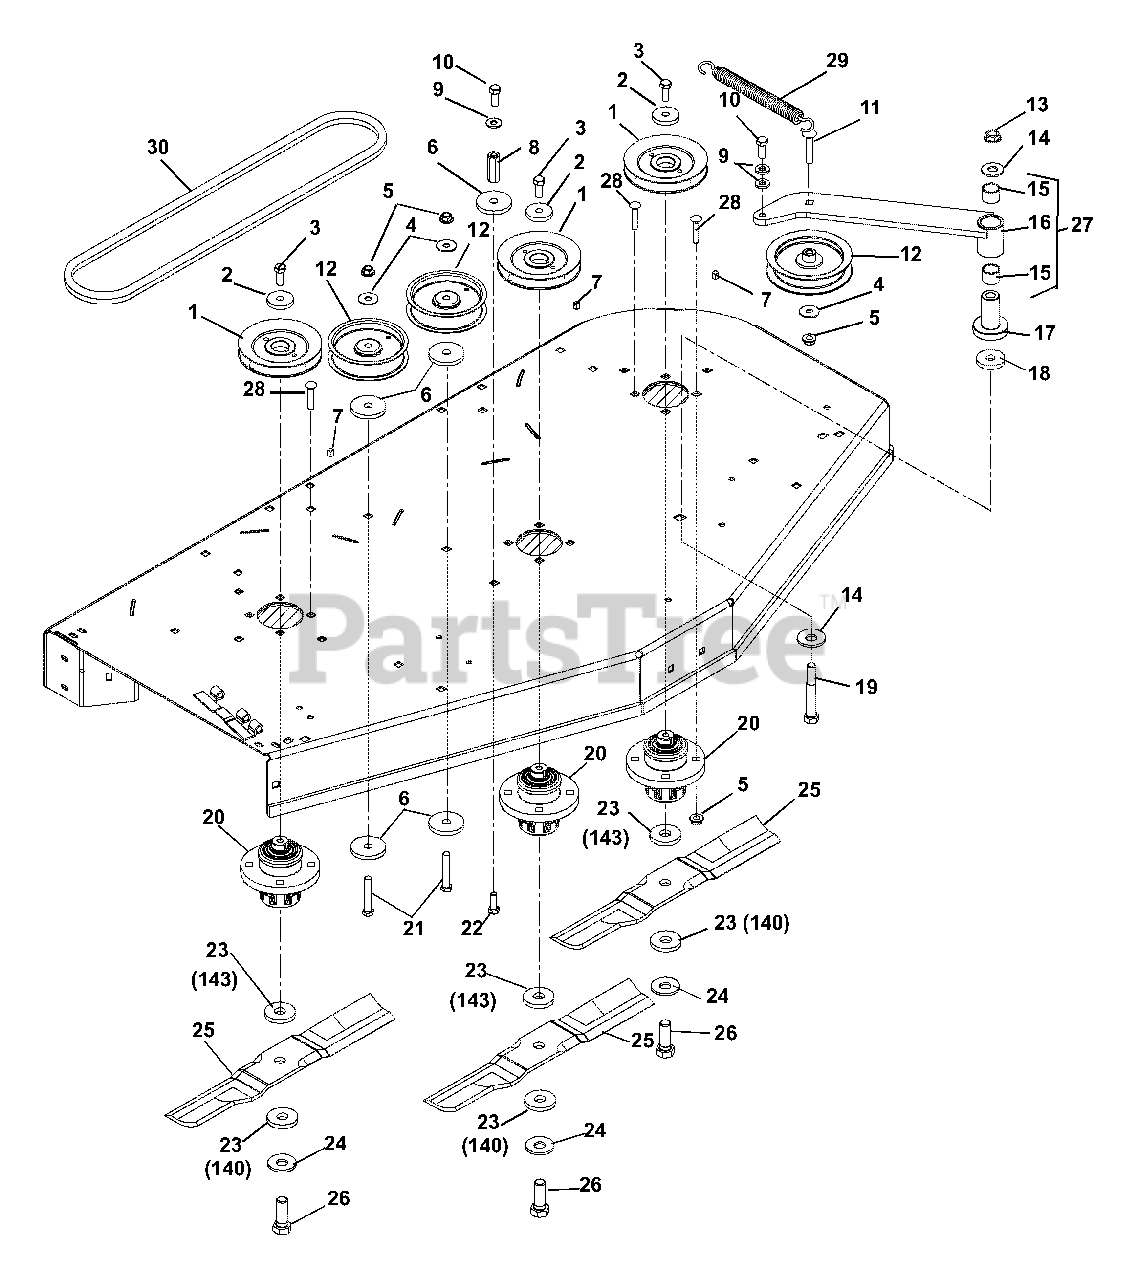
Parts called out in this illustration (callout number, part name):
1	Sheave, 32" Deck
2	Washer, Flat Steel .406 x 1.50 x .245
3	Bolt-Hex .38-16 x 1.00 Grade 8
4	Washer, Flat Steel .375 x 1.125 x .065
5	Nut, .38-16 Flange Nyloc
6	Washer, Flat Steel .469 x 2.00 x .25
7	Key, Square .25 x .38 x .25
8	Nut, Coupling .375-16 x 1.75
9	Washer, Flat Steel .38 x .875 x .083
10	Bolt, Shoulder EP .38-16 x .30
11	Bolt, Round Head Square Neck .38-16 x 2.00 Grade 5
12	Idler, Flat .38 x 4.00 x 1.06
13	Nut, Flange Nyloc .50-13
14	Washer, Flat Steel .531 x 1.250 x .10
15	Bearing, 1.00 x 1.12 x .75
16	Weldment, Idler Arm
17	Bearing, Pedestal
18	Washer, Flat Steel .531 x 3.00 x .25
19	Bolt, Hex .50-13 x 3.75 Grade 5
20	Assembly, Spindle
21	Bolt, Hex .38-16 x 2.25 Grade 5
22	Bolt, Hex .38-16 x 1.00
23	Washer, Flat .640 x 1.81 x .250
24	Washer, Beveled .63 x 1.625 x .14
25	Blade, Mower 16.19" (143)
25	Blade, Mower 15.50" (140)
26	Bolt, Hex .62-18 x 1.75 Grade 8
27	Assembly, Idler Arm
28	Bolt, Round Head Square Neck .38-16 x 1.50 Grade 5
29	Spring, Extension (Deck Idler)
30	V-Belt, HA x 142.7 EFF. Length
